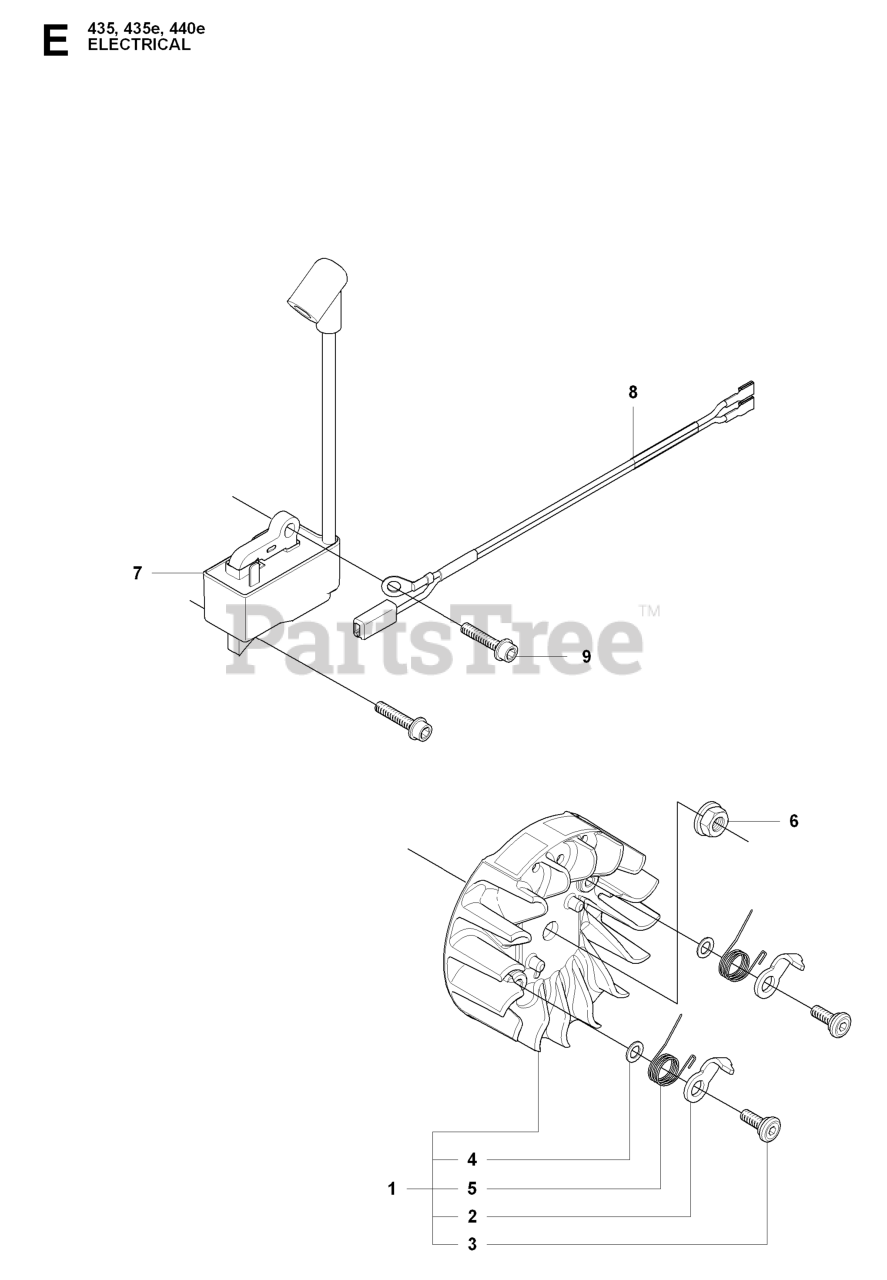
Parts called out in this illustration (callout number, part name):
1	%FLYWHEEL ASSY
2	PAWL
3	SCREW
4	WASHER
5	%SPRING, STARTER CATCH
6	NUT W/ WASHER
7	IGNITION MODULE
8	WIRING ASSY
9	SCREW
